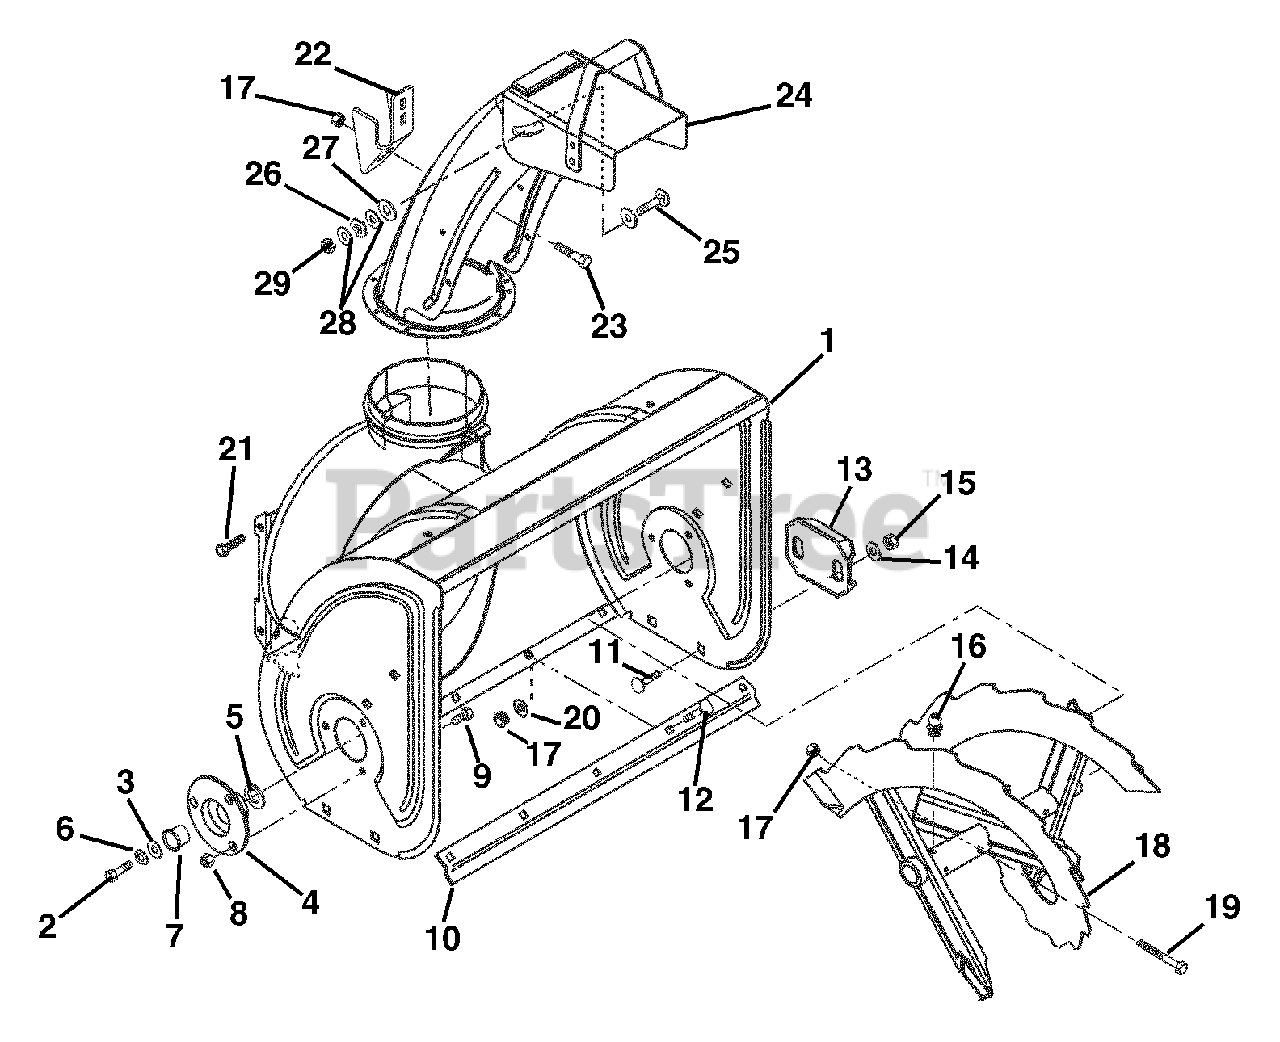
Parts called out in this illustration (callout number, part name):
1	HOUSING, BLOWER - 24"
2	@BLT-HEX .31-18X.50 GR5 YWZC
3	WSHR-FL-STL .347X1.254X.048YWZ
4	BEARING FLANGE ASSEMBLY
5	@WSHR-FL-STL.812X1.50X.135YWZC
6	@WSHR-LK .31X.078 REG YWZC
7	BSHG-FLG .750X1.000X.625X1.250
8	@NUT-SPNLK-FLG .25-20 YWZC
9	BLT-SERNK SL .25-20X.50 YWZC
10	SCRAPER BLADE
11	BLT-RHHDSQSHNK .38-16X.75 G2YZ
12	BLT-RDHDSQSHNK.25-20X.50 YWZC
13	SKID SHOE, REVERSIBLE - ORANGE
14	@WSHR-FL-STL.38X.875X.083 YWZC
15	@NUT-LK-CTR .38-16 YWZC
16	ZERK,FITTING .25X.125 DRIVE IN
17	@NUT-LK-CTR .25-20 YWZC
18	RAKE, RIGHT-24"(.75ID X 10.88)
19	SHEAR BOLT WITH NUT
20	@WSHR-FL-STL.281X.62X.065 YWZC
21	@SCR-TAP .38-16X.75 HWH TR YWZ
22	CHUTE STRAP
23	@BLT-HEX .25-20X.50 GR5 YWZC
24	CHUTE, DISCHARGE W/CAP & DECAL
25	@BLT-RHDSSQNK .31-18X.75 G5YZ
26	WAVE WASHER .390X.655X.110
27	WSHR-PLASTIC .390X.875X.062
28	@WSHR-FL-STL.344X.688X.065YWZC
29	@NUT-LK-CTR .31-18 YWZC
